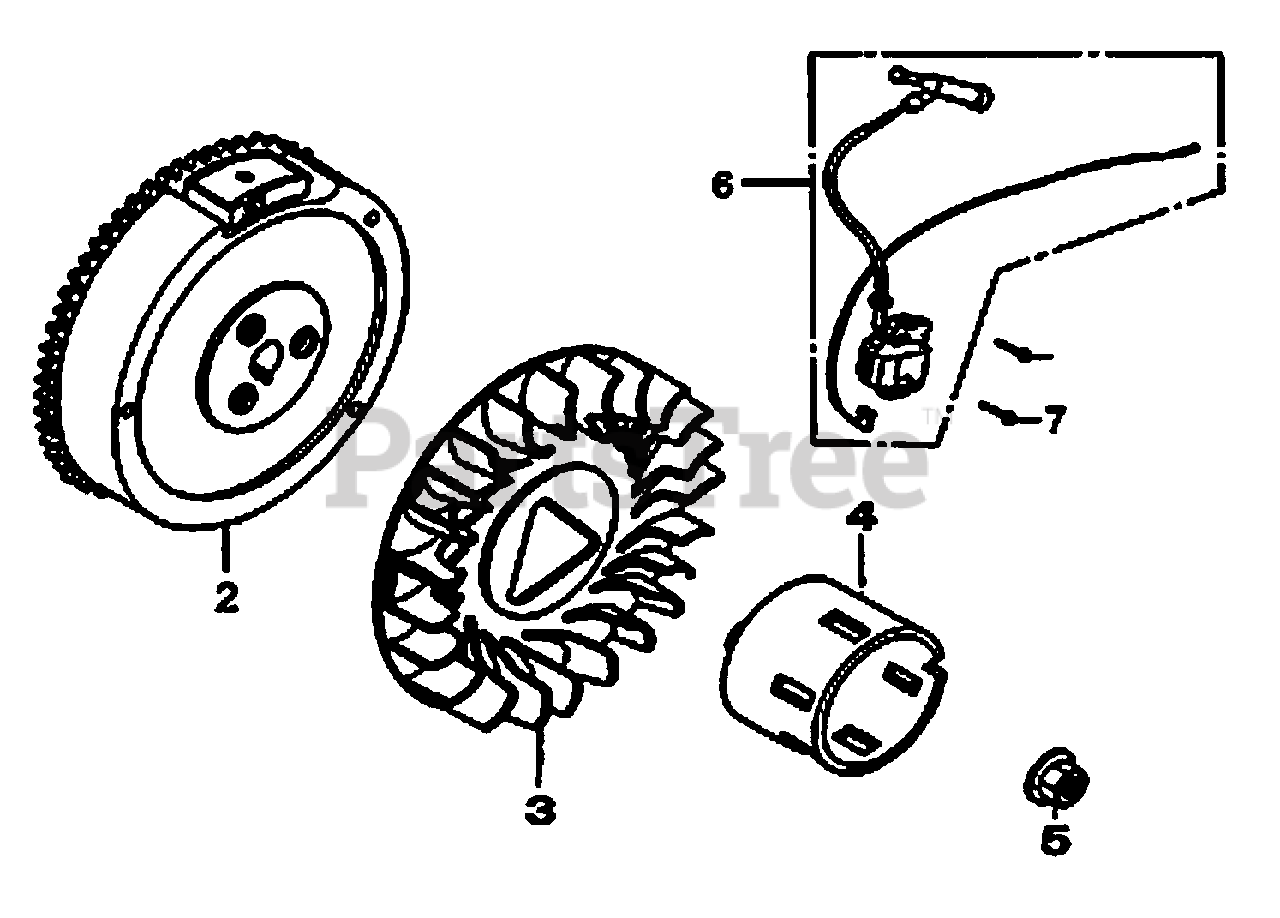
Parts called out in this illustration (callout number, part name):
2	FLYWHEEL COMP.
3	FAN COOLING
4	PULLEY, STARTER
5	NUT SPECIAL, M16
6	COIL ASSY., IGNITION
7	BOLT, FLANGE, M6X25
